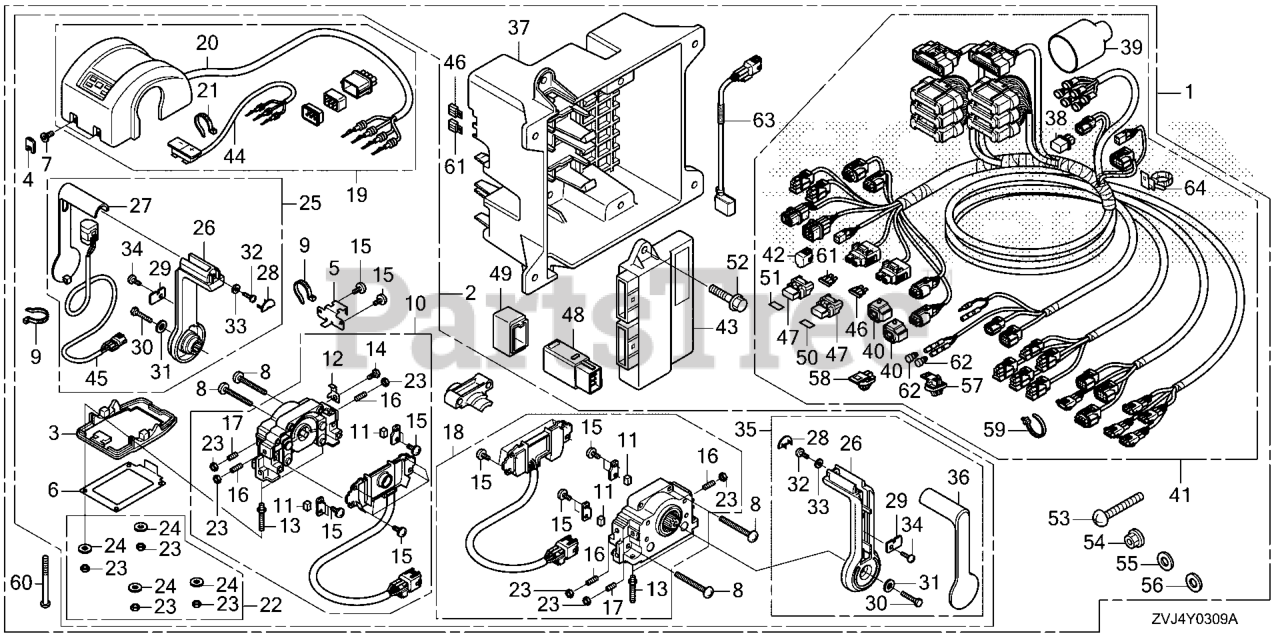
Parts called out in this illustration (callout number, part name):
1	BOX KIT, REMOTE CONTROL (TOP MOUNT DUAL)(MAIN)
1	BOX KIT, R/C
2	BOX ASSY., REMOTE CONTROL (TOP MOUNT DUAL)(RH)
3	GASKET (TWIN)
4	COVER, CAP
5	PLATE, COVER FIX (TWIN)
6	SHEET, WATERPROOF (TWIN)
7	BOLT, SOCKET
8	SCREW
9	BAND, NYLON
10	HOUSING ASSY., L.
11	SHOE, BRAKE
12	PLATE, HARNESS
13	BOLT, STUD
14	BOLT
16	SCREW SET
17	SCREW SET
18	HOUSING ASSY., R.
19	COVER ASSY., TWIN
20	LED ASSY., COVER (T)
21	BAND, NYLON
22	NUT SET, MOUNTING
24	WASHER
25	LEVER ASSY., L.
26	LEVER
27	PANEL, LEVER (POWER TRIM-TILT)
28	CAP, LEVER
29	PLATE, LEVER PANEL
30	BOLT
31	WASHER
32	SCREW
33	WASHER
34	SCREW
35	LEVER ASSY., R.
36	PANEL, LEVER
37	CASE, CONTROL UNIT
38	TERMINATOR ASSY.
39	COVER, CONNECTOR (NOT AVAILABLE)
40	SUSPENSION, CONNECTOR
41	CABLE ASSY., REMOTE CONTROL (MAIN)
41	CABLE, REMOTE CONTL
42	CAP, DUMMY (WPC 4P 090 M) (RED)
43	UNIT ASSY., CONTL
44	SWITCH ASSY., SELECT
45	SWITCH ASSY., POWER TRIM-TILT
46	FUSE, BLADE (3A)
47	COVER ASSY., FUSE
48	RELAY ASSY., MAIN
49	SUSPENSION, RELAY
50	LABEL, FUSE (3A)
51	LABEL, FUSE (5A)
52	BOLT, FLANGE (6X20)
53	SCREW, PAN (5X40) DUAL QTY = (8) (SINGLE)
54	NUT, FLANGE (5MM)
55	WASHER, PLAIN (5MM)
56	WASHER, SPRING (5MM)
56	WASHER, SPG (5MM)
57	CLIP, CONNECTOR (DARK BLUE)
58	CLIP, CONNECTOR (DARK BROWN)
59	CLIP, HARNESS BAND (145MM) (BLACK)
60	SCREW, PAN (5X65)
61	FUSE, MINI (5A)
62	PLUG, CONNECTOR (INNER) (TROLLING CONTROL)
63	RELAY ASSY., CONTROL (NOT AVAILABLE)
64	HOLDER, CONNECTOR (128.6MM) (NATURAL)
